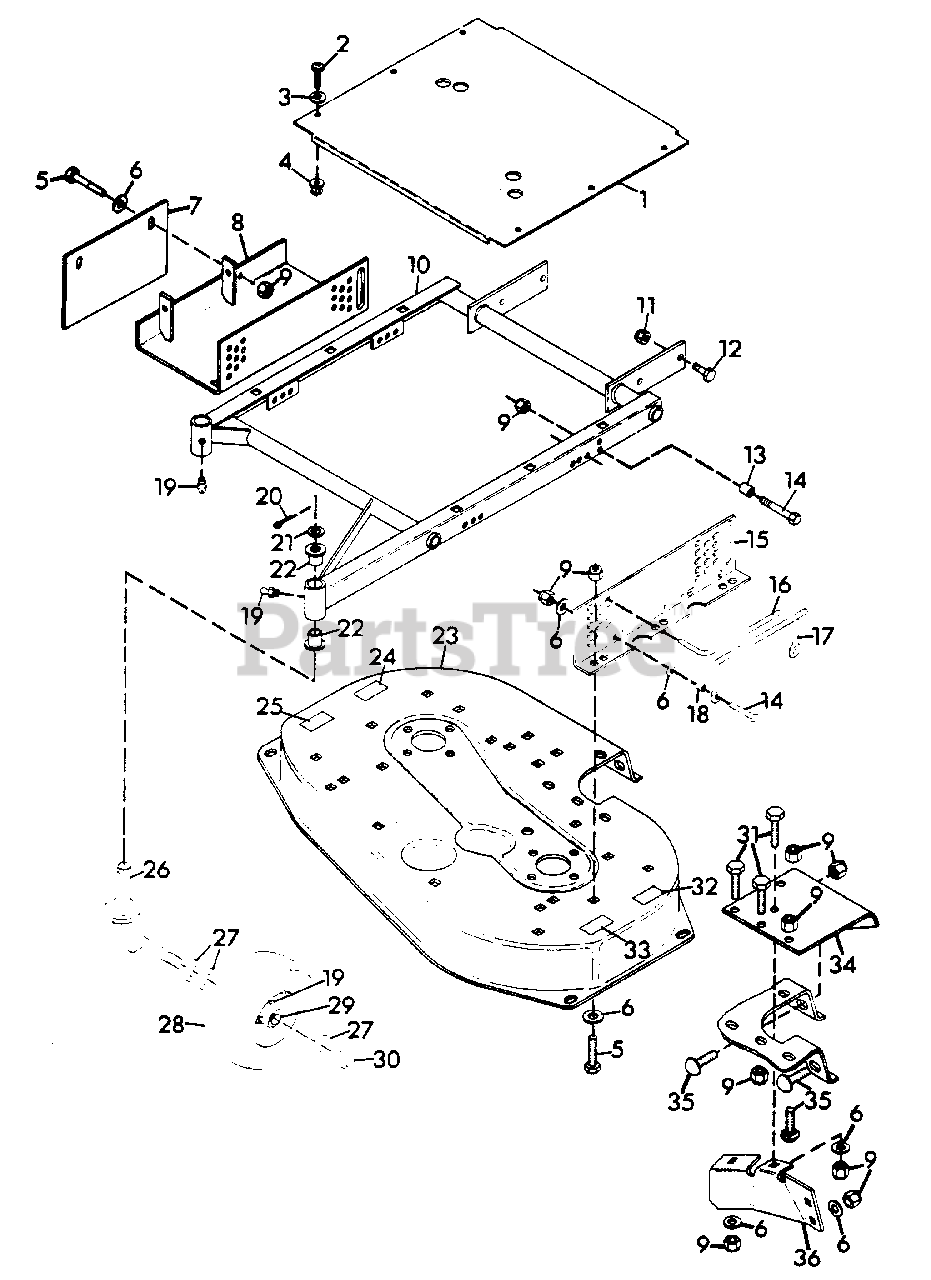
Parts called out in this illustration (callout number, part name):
1	Cover, Silkscreen 40" Mower
2	Screw, Tapping 1/4-20x.625 P/Hd
3	Washer, Flat .281x.625x.065
4	Grommet, Plastic
5	Bolt, Hex 3/8-16x1.00
6	Washer, Flat .406x.812x.065
7	Plate, Discharge Cover
8	Weldment, Mower Support Brkt.
9	Nut, Lock 3/8-16
10	Weldment, Mower Frame
11	Nut, Lock 5/8-11
12	Bolt, Hex 5/8-11x1.50
13	Bushing .391x.622x.670
14	Bolt, Hex 3/8-16x1.50
15	Bracket, Mower Side Support R.H.
16	Pin, Mower Locking
17	Handle
18	Bushing
19	Fitting, Lube 1/4-28
20	Pin, Cotter .187x1.50
21	Race, Bearing Thrust
22	Bushing, Pivot
23	Deck, 40" Mower
24	Decal, Caution
25	Decal, Danger Foot
26	Weldment, Caster Fork
27	Washer,Flat .812x1.496x.134
28	Wheel, Gauge
29	Bearing, Gauge Wheel
30	Nut, Lock 3/4-10
31	Bolt, Hex 3/8-16x1.25
32	Decal, Warning Eye
33	Decal, Danger Hand
34	Shield, Discharge
35	Bolt, 3/8-16x1.00 Rd Hd Sq Nk
36	Shroud, Blade
